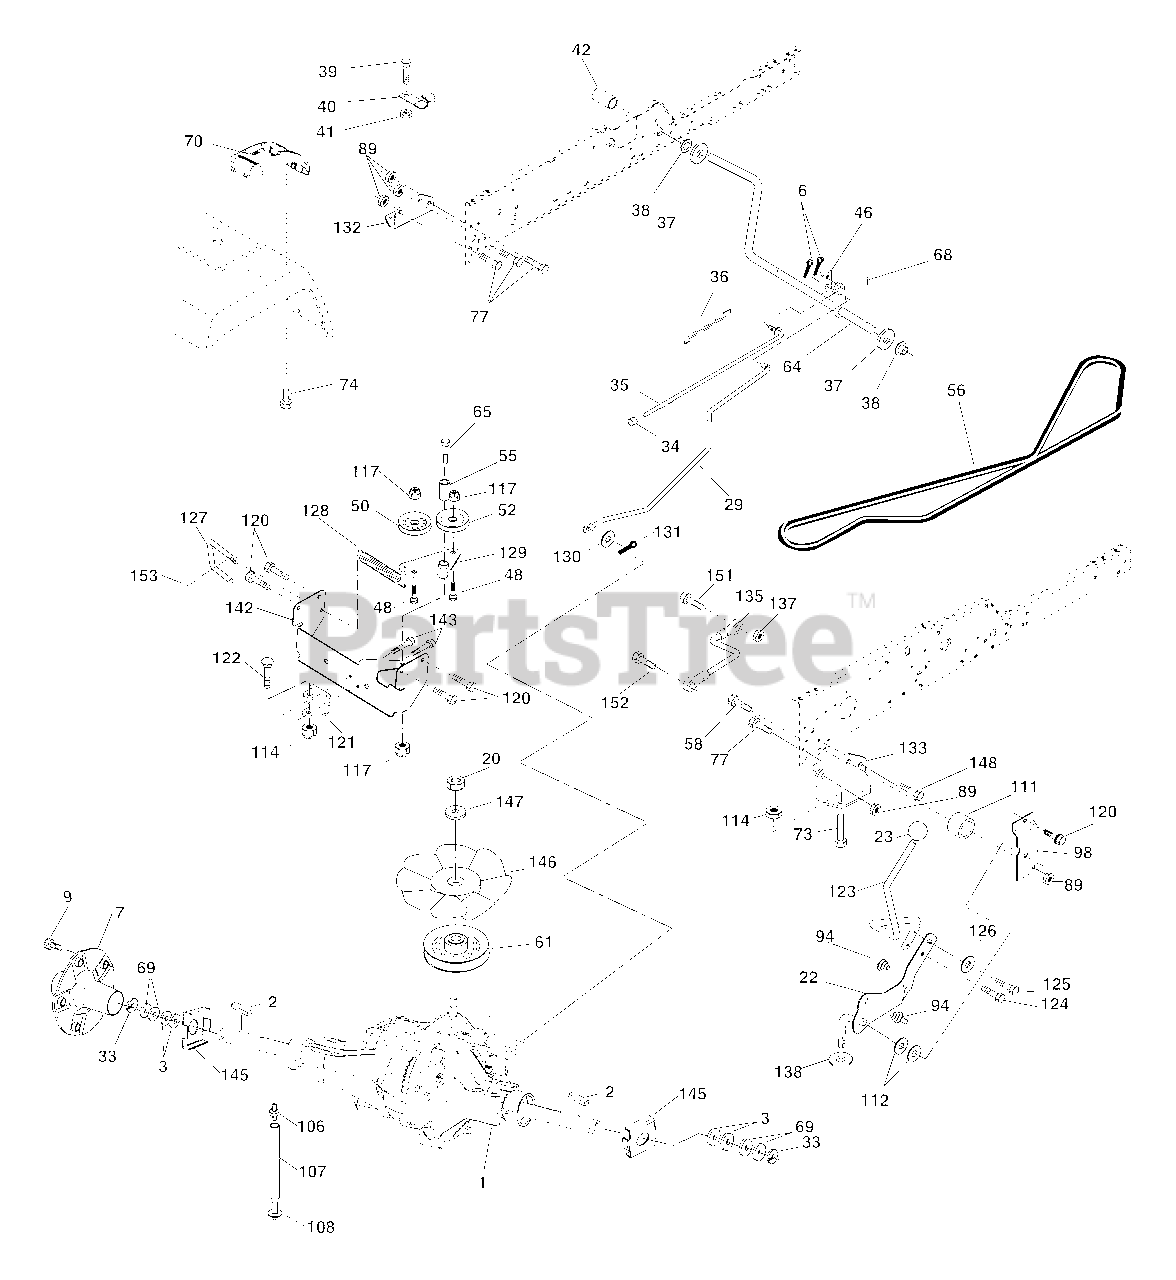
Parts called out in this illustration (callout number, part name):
2	Key 1/4 x 2.5
6	Pin, Cotter
7	Wheel, Hub Assembly
22	Lever Asm Shift
29	Brake, Rod
34	Cap, Parking Brake
35	Rod, Parking Brake
36	Spring, Drive Ground
37	Washer 25/32 x 1-1/4 x 16 Ga.
39	Screw, Fin. #10-24 x 1
40	Actuator, Interlock VGT
41	Nut Centerlock 10-24 Unc
42	Cover, Pedal
46	Retainer, Spring
48	Bolt Rdhd 3/8-16 x 1.3/4 Gr. 5
50	Pulley, Idler, Flat
52	Pulley, Idler, Grooved
53	Washer Hardened
55	Bearing, Idler
58	Bolt Fin Hex 7/16-14 x 1-1/2
61	Pulley, Transaxle
64	Shaft, Brake Pedal
65	Bolt, Shoulder
70	Console Automatic YT/GT
73	Bolt Hex Flghd 5/16-18 x 3 Gr5
74	Screw Hex Wsh. Hi-Lo 1/4-1/2
77	Bolt Fin Hex 7/16-14 x 1
89	Nut Crownlock 7/16-14 Unc
94	Fastener Christmas Tree
98	Bracket Shift
106	O-Ring Asm Hydro Gear
107	Line Fuel Hydro 15" VGT
108	Cap Asm Vent Hydro Gear
111	Spacer Shift Lever VGTH
112	Washer Nylon High Temp
114	Nut Lock Hex W/Ins 5/16-18 Unc
117	Nut, Lock Flg. 3/8-16
120	Screw 3/8-16 x .75
121	Bracket Strap Torque
122	Bolt RDHDSQ 5/16-18 Unc x 2-1/2
124	Bolt Shoulder 5/16-18 x .561
125	Screw 5/16-18 x 5/8
126	Washer SRRTD 5/16 ID x 1.0 x .125
127	Link Control Clutch
128	Spring Drive GRND
129	Bracket Asm Idler Tensioning
130	Washer 13/32 x 5/8 x 16 Ga.
131	Pin Cotter 3/32 x 3/4
132	Bracket Mtg Hydro 3500 LH VGT
133	Bracket Mtg Hydro 3500 RH VGT
135	Link Asm Control Hydro 3500
137	Nut Lock 5/16-18 NC Thd.
138	Washer Thrust 5/8 x 1.10 x 1/32
142	Strap Torque HG-3500
145	Washer Axle Flange HG-3000
146	Fan 7" Hydro
148	Screw 3/8-16 x 1-1/4
151	Bolt Hex 5/16-18 x 7/8
152	Bolt Hex 5/16 x 1 W/Patch
153	Spring, Retainer
